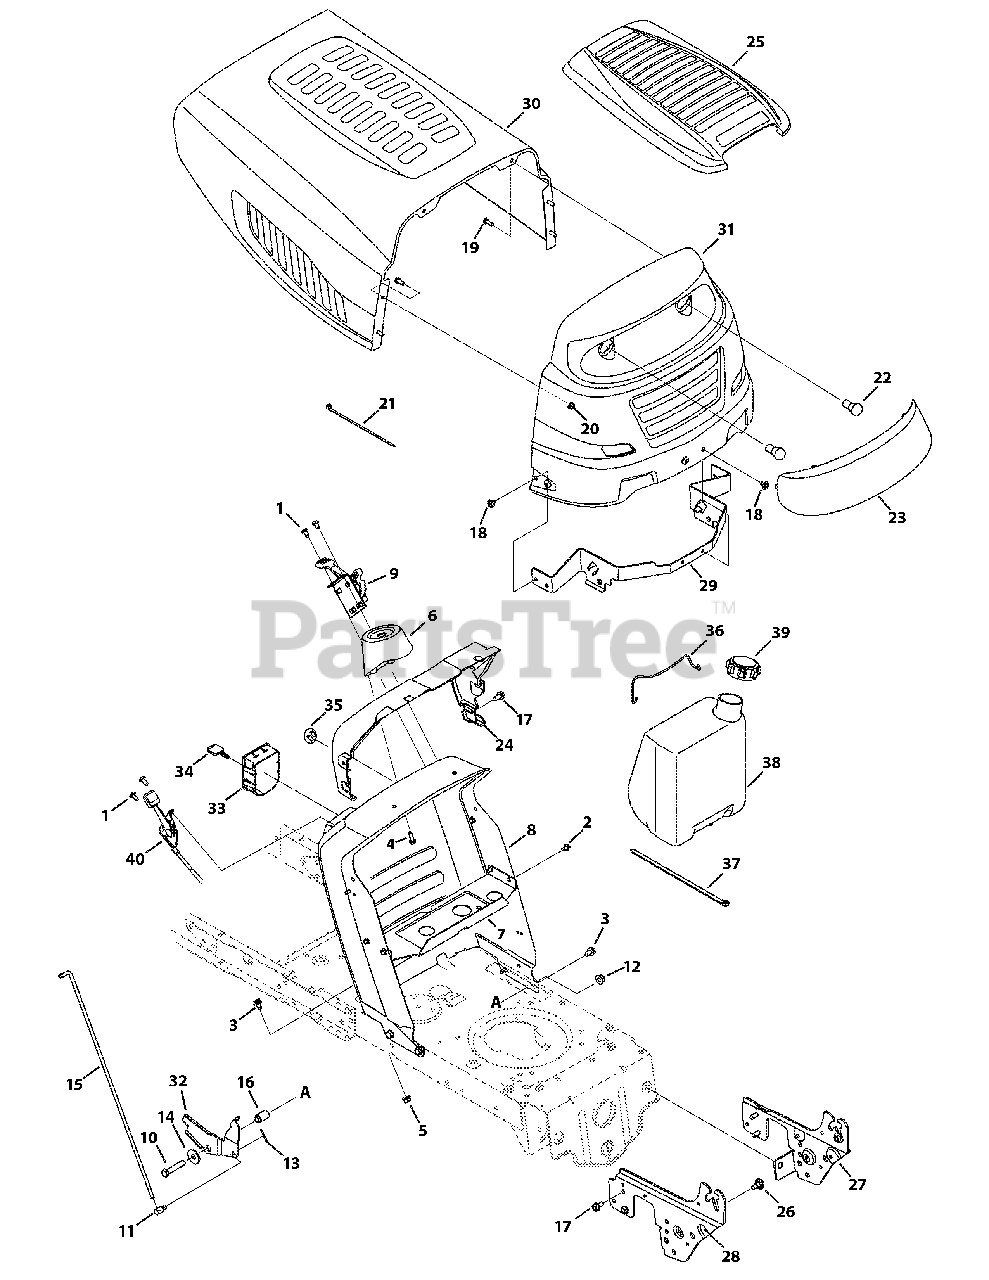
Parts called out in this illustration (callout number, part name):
1	Screw, 1/4-20 x .500
2	Hex Index Washer Screw, 1/4-20 x .500
3	Screw, 5/16-18 x .625
4	Screw, 1/4-15 x .750
5	Flangelock Nut, 5/16-18
6	Steering Support
7	Gas Tank Support Bracket
8	Dash, No RMC
9	7-speed Control Assembly
10	Hex Screw, 3/8-16 x 2.0
11	Ferrule, 1/4-20 x 1.0
12	Flangelock Nut, 3/8-16
13	Cotter Pin, 3/32 x 1.0
14	Flat Washer, .411 x 1.25 x .100
15	Speed Selector Control Rod
16	Flange Spacer, .390 x .671 x 1.095
17	Screw, 5/16-18 x .750
18	Screw, 5/16-18 x .375
19	Hex Screw, 1/4-20 x .620
20	Flangelock Nut, 1/4-20
21	Cable Tie
22	Miniature Lamp, 12V
23	Grill Lens
25	Hood Cover
26	Shoulder Screw, 5/16-18, .43 x .29
27	Left-hand Support Pivot Bracket
28	Right-hand Support Pivot Bracket
29	Hood Pivot Bracket
30	Hood - Red
31	Grill - Red
33	Key Switch
35	Choke Plug
36	Battery Rod
37	Cable Tie
38	Fuel Tank, 1.5 Gallon
39	Fuel Cap
40	Throttle/Choke Cable
